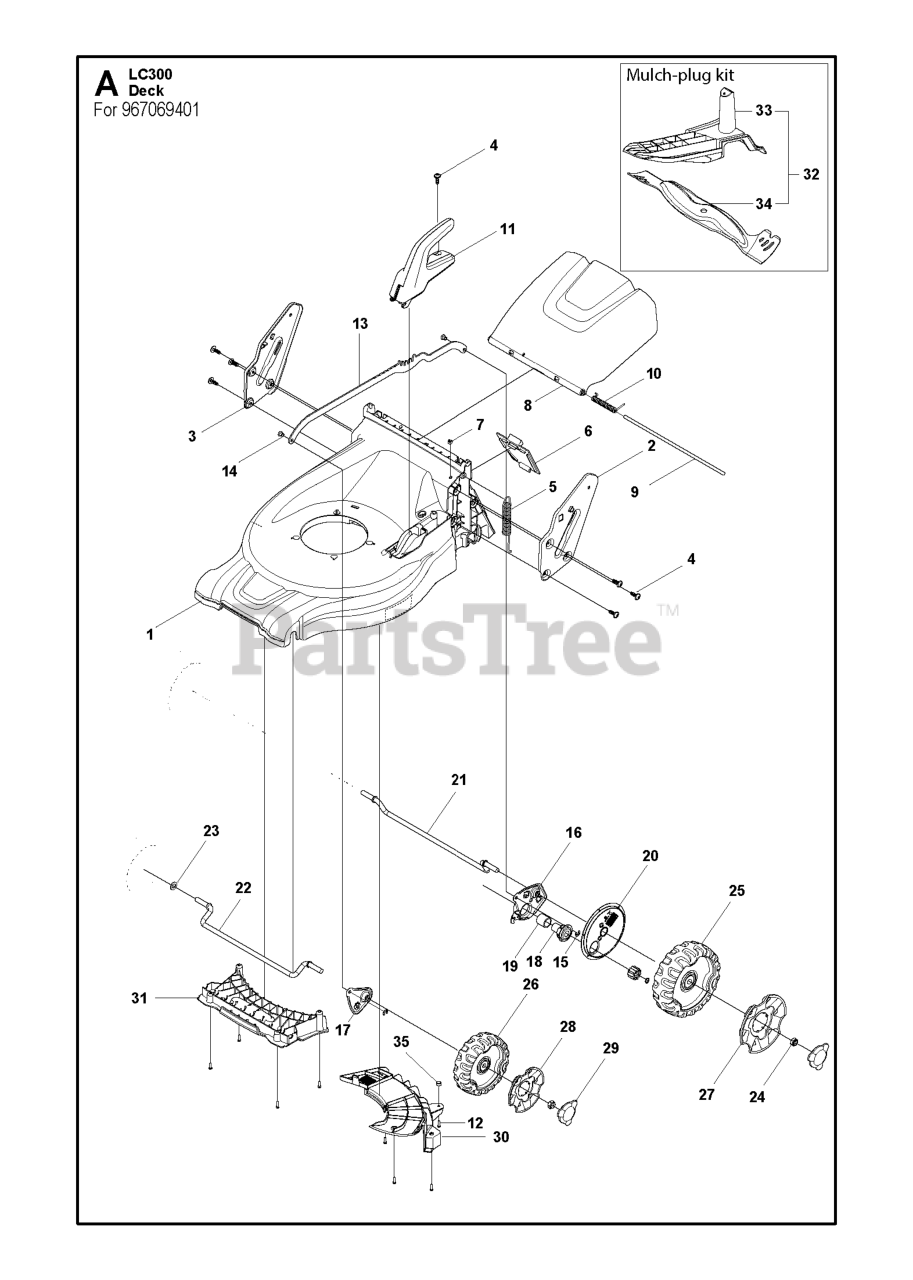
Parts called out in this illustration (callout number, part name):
8	FUEL PUMP DIAPHRAGM
12	SCREW ITXPANT T50X16 ZN/FE (A
15	Retaining Ring
